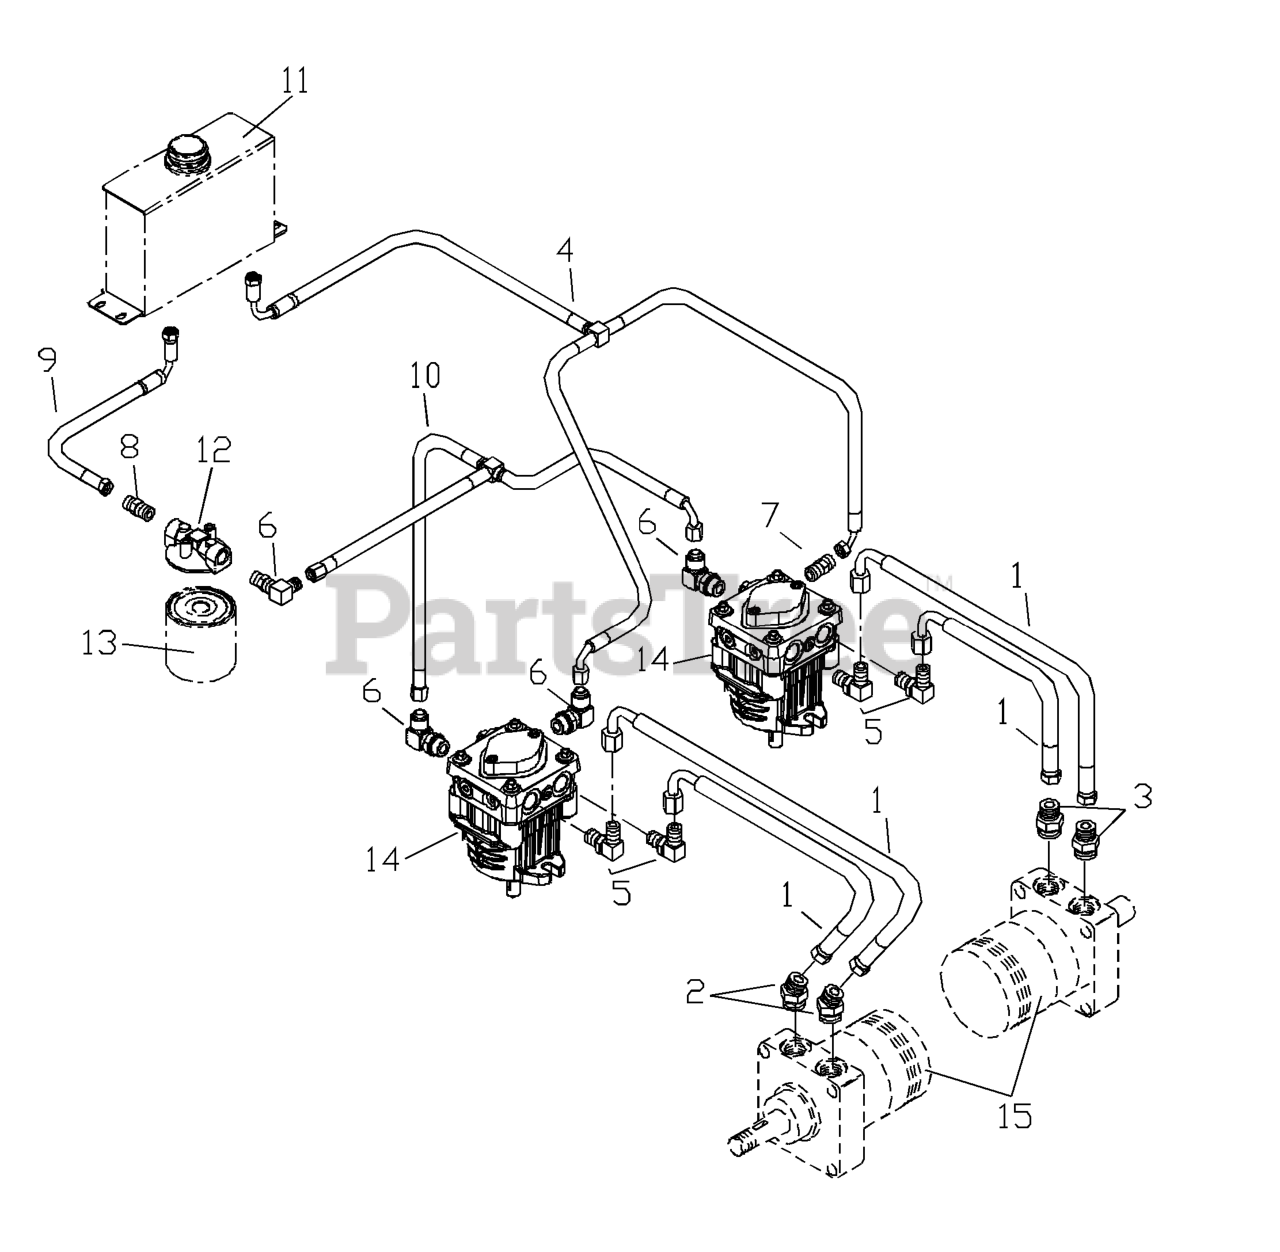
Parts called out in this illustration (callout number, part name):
1	HOSE, 1/2" HYDRAULIC
2	ELBOW-ADJ 45 DEG F6802-8-10
3	CONNECTOR, STRAIGHT
4	INLET TEE HOSE
5	ELBOW, 90 DEGREE
6	ELBOW, F6801-6-6-0 90 DEGREE
8	STRAIGHT FITG
9	HOSE
10	RETURN TEE HOSE
11	OIL TANK BLK
12	FILTER HEAD
13	HYDRAULIC OIL FILTER
14	PUMP
15	WHEEL MOTOR
